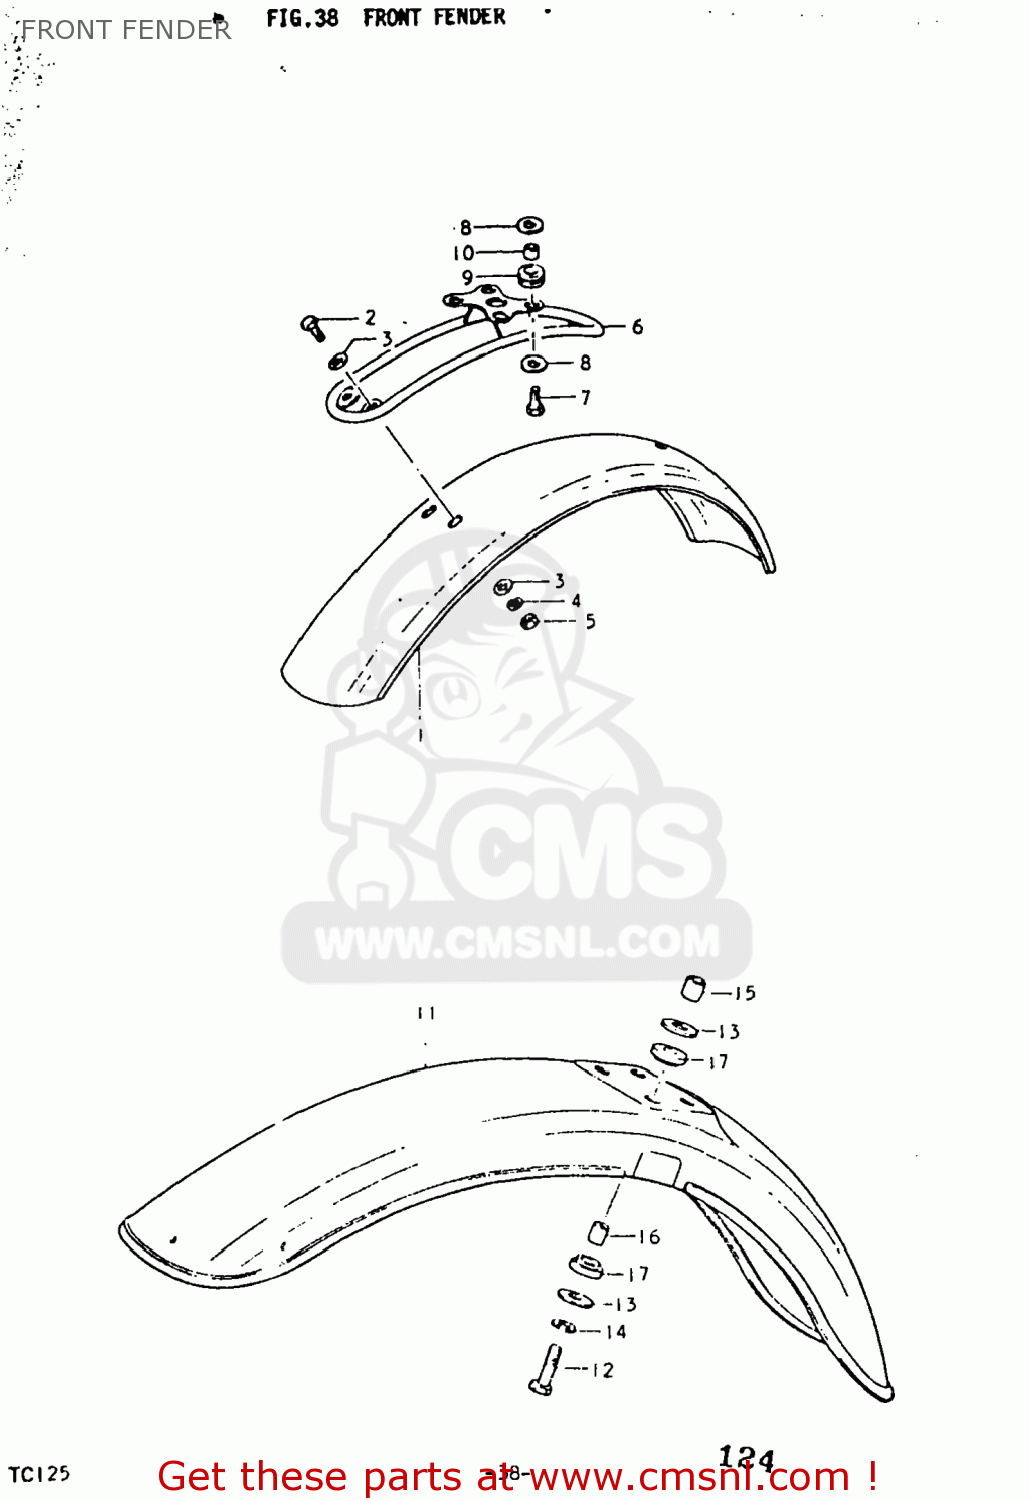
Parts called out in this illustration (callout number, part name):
1	FENDER,FRONT
2	BOLT, FRONT FENDER K,L,M
3	WASHER
4	LOCK WASHER
5	NUT
6	BRACE,FRONT FENDER
7	BOLT
8	WASHER (6.5X20X1.2)
9	CUSHION
10	SPACER(6.1X9X7.5)
11	FENDER,FRONT
12	BOLT
13	WASHER (6.5X24X1.2)
14	LOCK WASHER
15	SPACER
16	SPACER (6.5X10.5X13.5)
17	CUSHION
